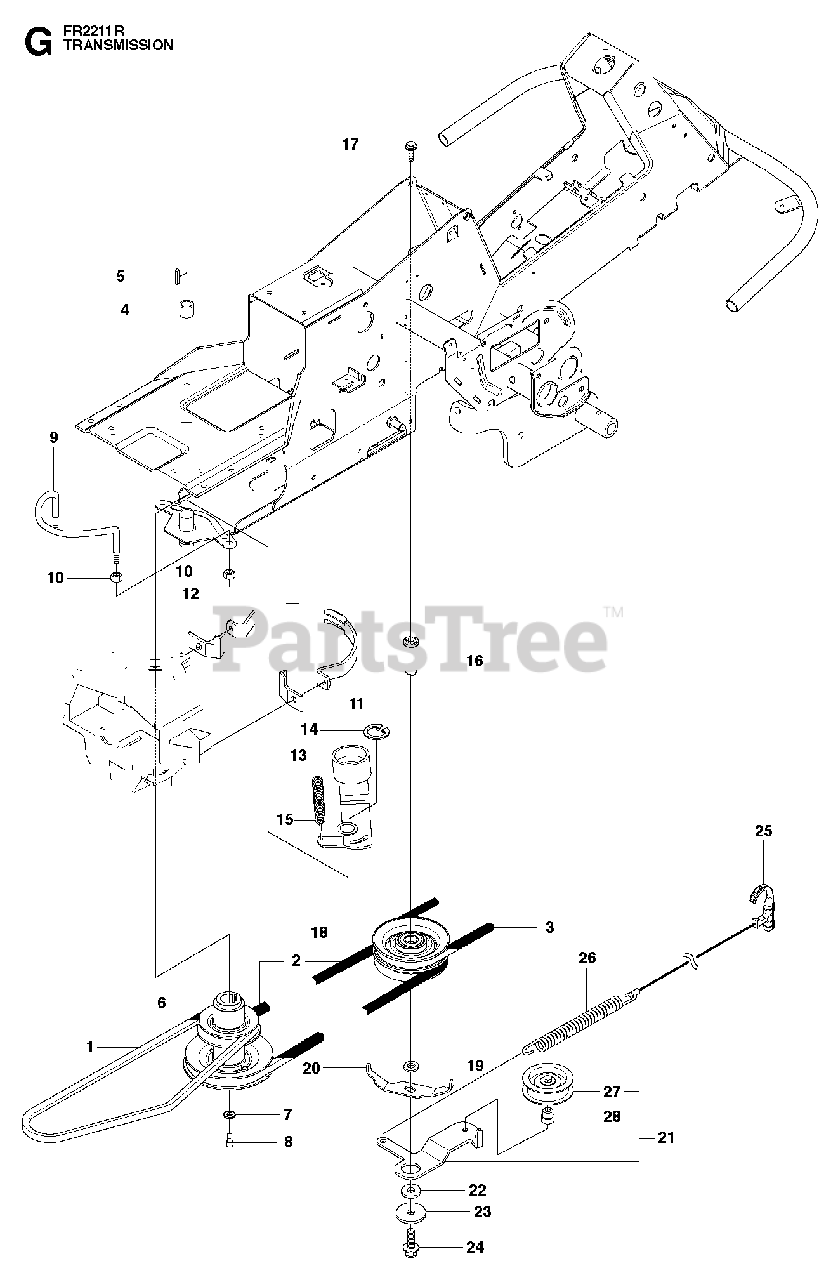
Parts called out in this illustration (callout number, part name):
1	TRANSMISSION BELT
2	BELT
6	PULLEY CPL
9	BELT GUIDE
11	BELT GUIDE CPL., RIGHT
12	BELT GUIDE CPL.,LEFT
13	TENSIONER
14	RETAINING RING SGA 25
16	SHAFT
20	BELT GUIDE
24	BOLT
